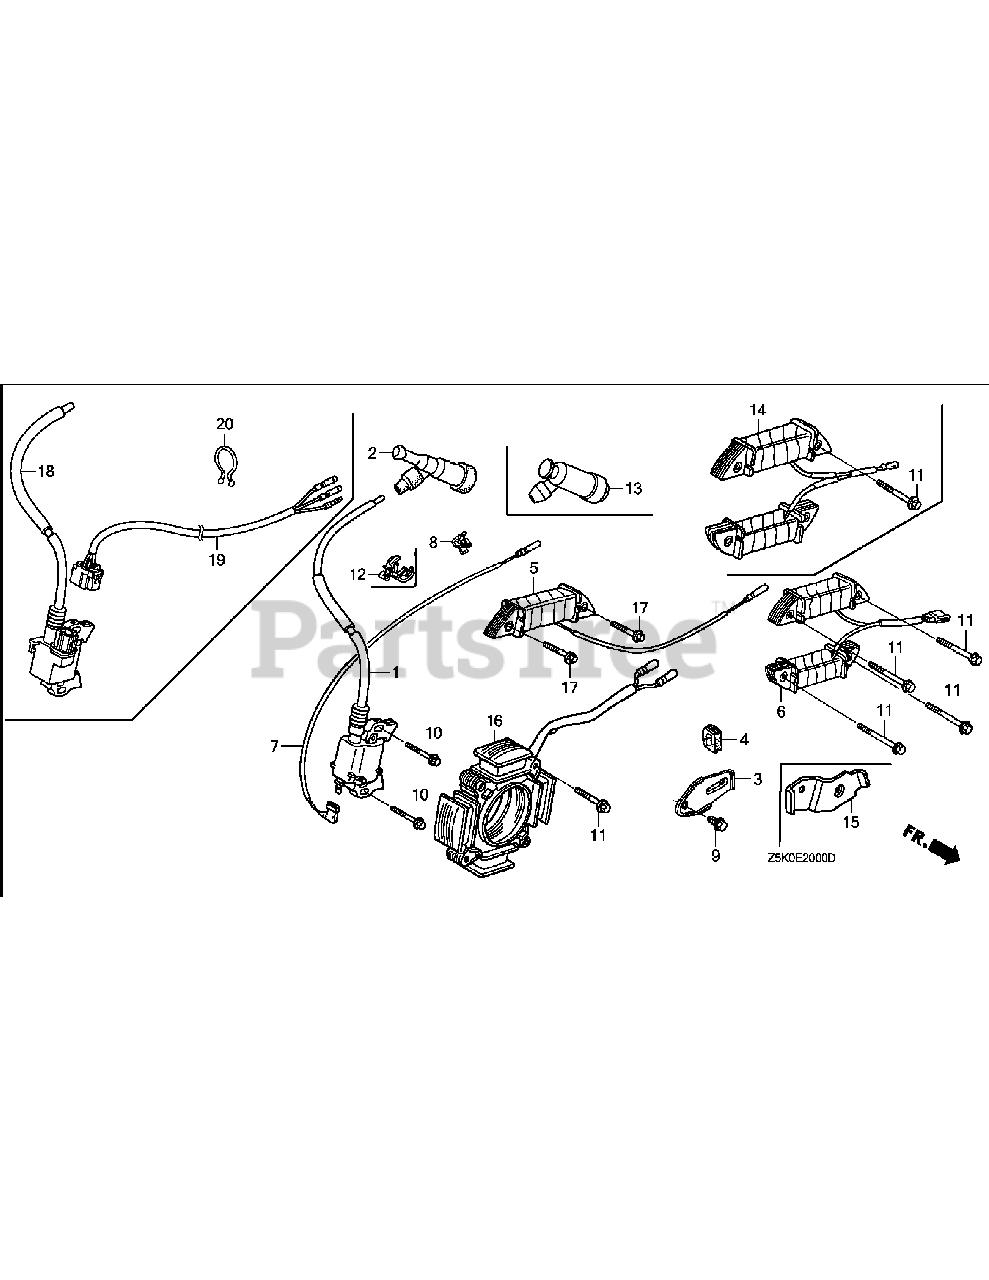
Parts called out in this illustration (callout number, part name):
1	Coil Assy., Ignition
2	Cap Assy., Noise Suppressor(Ngk Y-Ezd)
3	Clamper, Cord
4	Grommet, Cord
5	Coil Assy., Charge(3A)
5	Coil Assy., Charge(1A)
5	Coil Assy., Lamp(12V/25W)
6	Coil Assy., Charge(10A)
7	Cord, Stop Switch(370Mm)
8	Holder, Stop Switch Cord
9	Bolt, Flange, 6X12(Ct200)
10	Bolt, Flange, 6X28(Ct200)
11	Bolt, Flange, 6X28(Ct200)
12	Clip, Harness
13	Cap Assy., Noise Suppressor
14	Coil Assy., Lamp(12V/50W)
15	Clamper, Cord
16	Coil Assy., Charge(12V/18A)
17	Bolt, Flange, 6X32(Ct200)
18	Coil Assy., Ignition
19	Harness Assy., Engine Wire
20	Clip, Purse Lock
